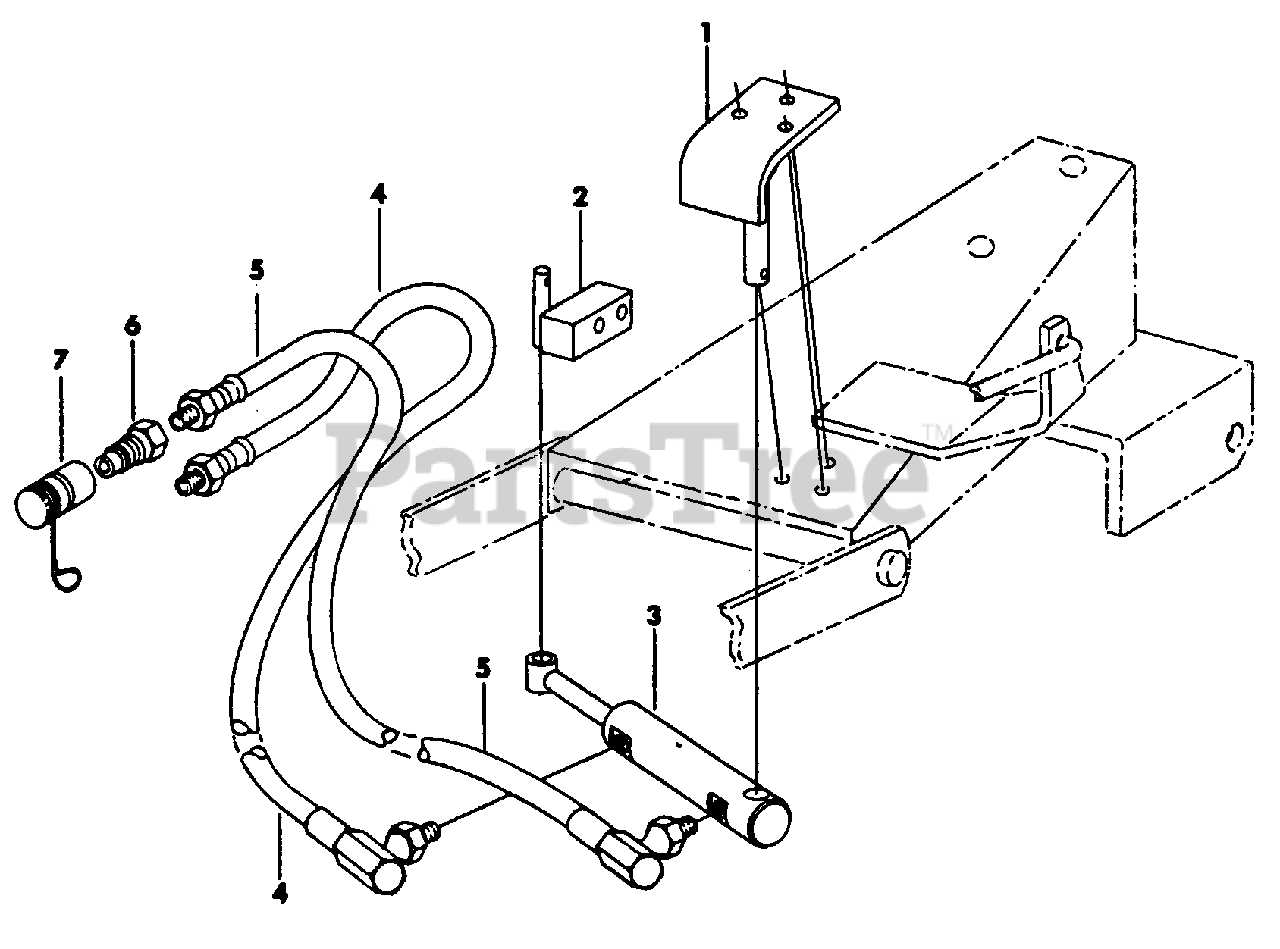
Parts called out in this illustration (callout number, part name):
1	Bracket Assy, Rear
2	Bracket Assy, Front
3	Cylinder Assy, 1-1/2 X 7-1/2 Hydraulic
4	Hose, 15 Inch -For Use w/61 904 C91 Attachment
5	Hose, 22 Inch
6	Nose Piece Assy
7	Cap, Hydraulic Coupling
